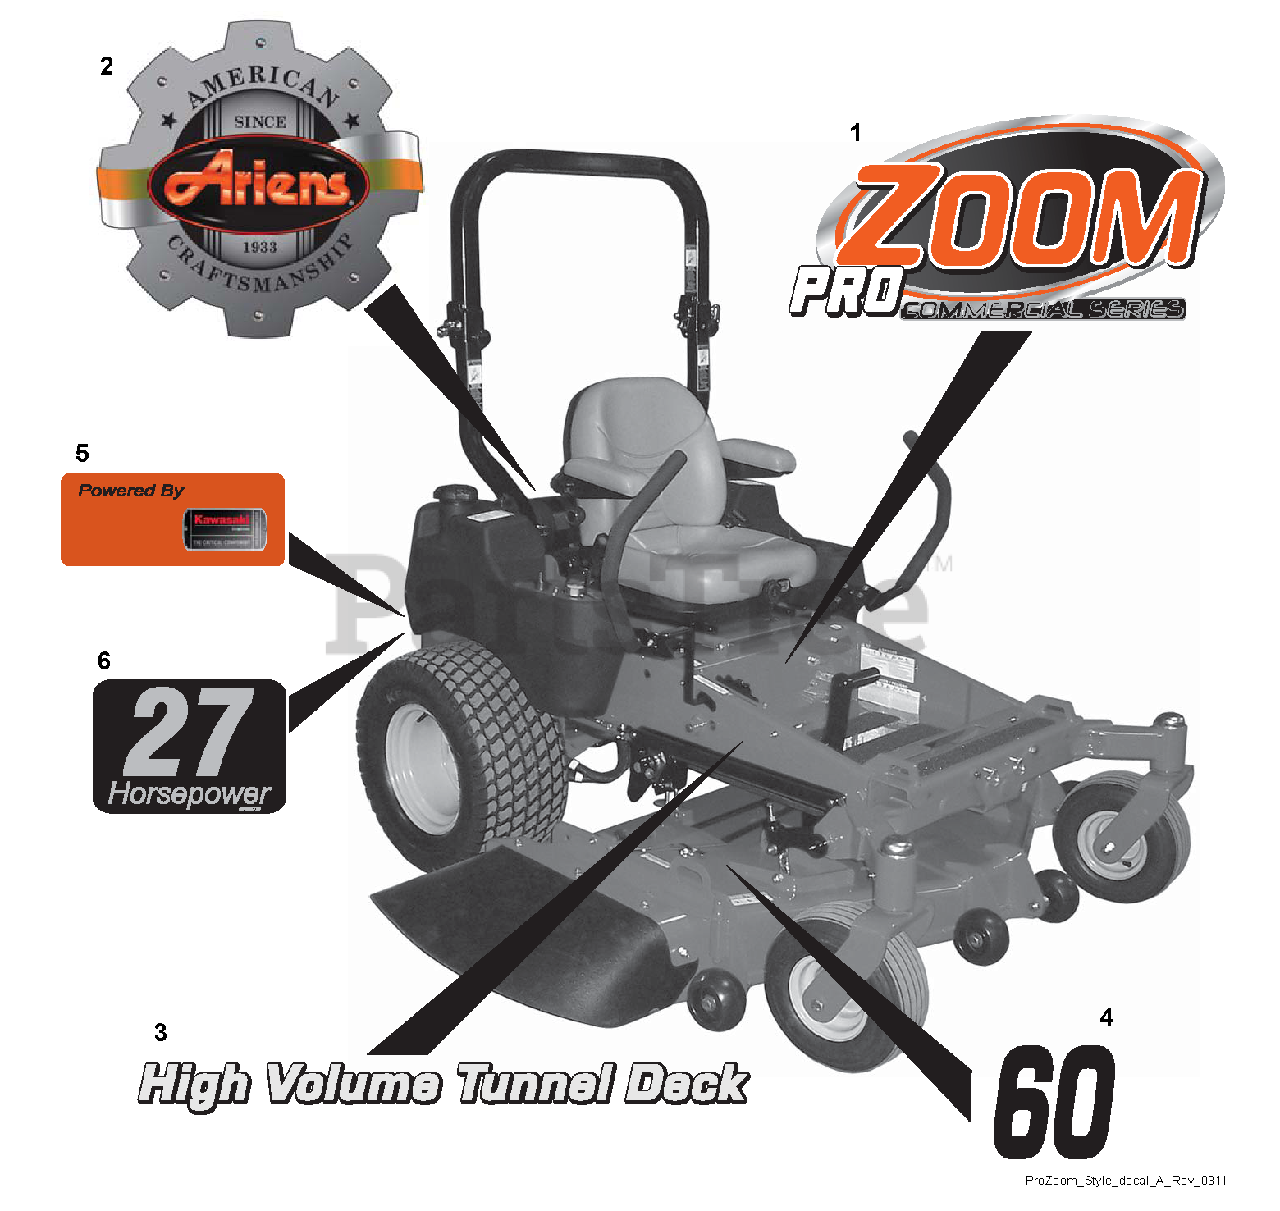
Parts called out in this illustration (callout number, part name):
1	DECAL, ARIENS PROZOOM 5.57"
2	Decal, Ariens Heritage, Large
3	DECAL, DECK FEATURES
4	DECAL, 54"
5	DECAL, POWERED BY KAWASAKI
6	DECAL, 27 HP
